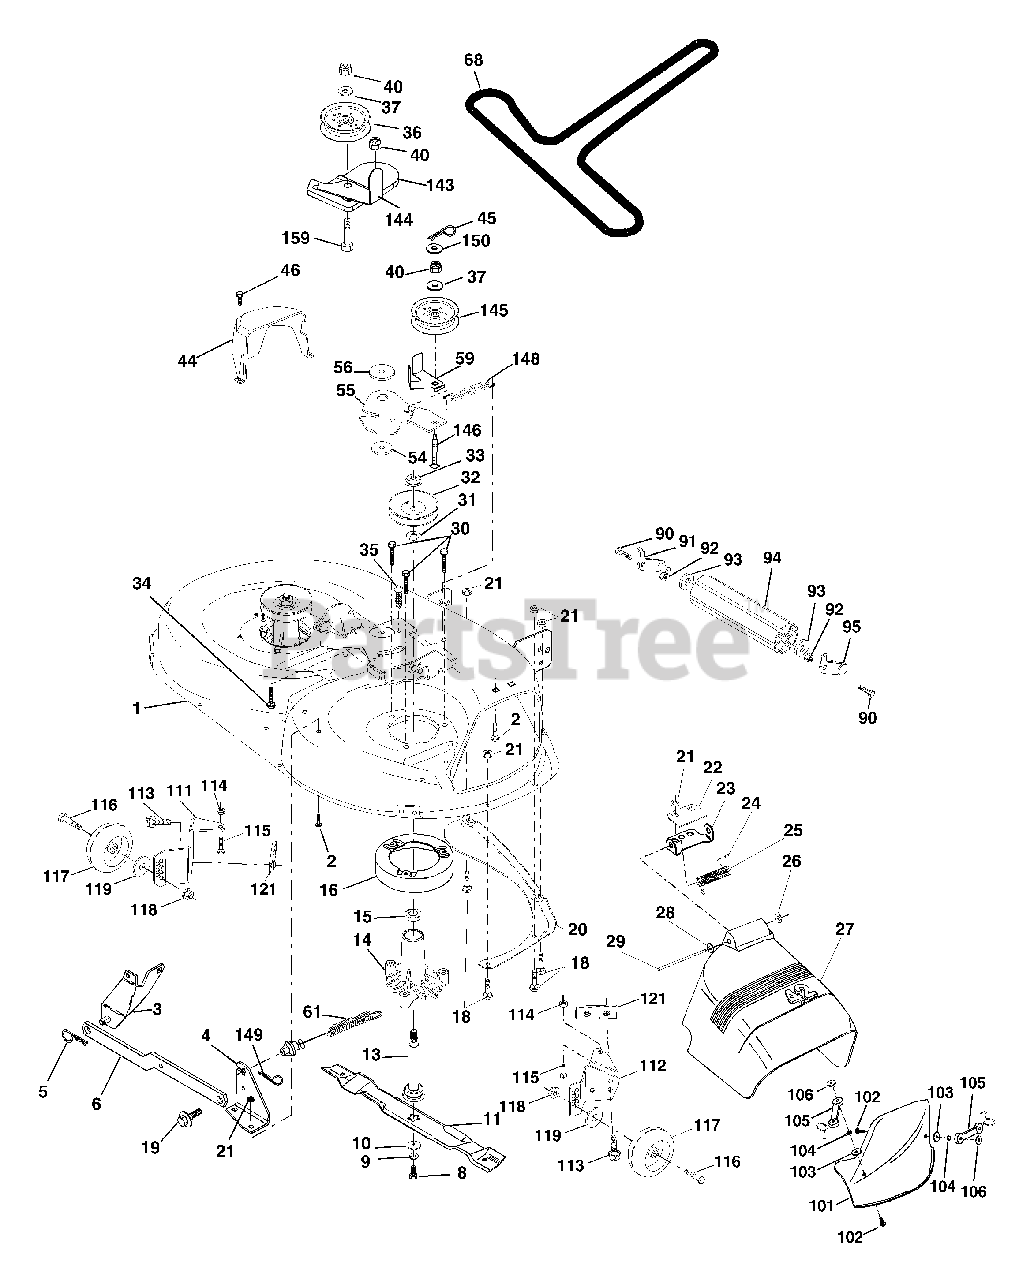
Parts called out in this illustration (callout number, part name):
1	Mower Deck Assembly, 42"
2	Bolt
3	Bracket Assembly,Sway Bar, Front
4	Bracket Sway Bar 38/42" Deck
5	Retainer Spring
6	Arm, Suspension, Rear
8	Bolt, Hex 3/8-24 x 1.25 Gr. 8
9	Washer, Lock
10	Washer,Hardened
11	Blade Mower 42" High Perf.
11	Blade, Mulching
13	Shaft Assembly, Mandrel, Vented
14	Housing, Mandrel, Vented
15	Bearing, Ball, Mandrel
16	Stripper, Vented Mower Deck
18	Bolt, Carriage 5/16-18 x 5/8
19	Bolt, Shoulder
20	Baffle, Vortex
21	Nut Crownlock 5/16-18 UNC
22	Stiffener Bracket
23	Bracket, Deflector
24	Cap, Sleeve
25	Spring, Torsion, Deflector
27	Shield, Deflector
28	Washer 11/32 x 5/8 x 16 Ga.
29	Rod, Hinge
30	Screw Thdrol Washer Head
31	Washer, Spacer
32	Pulley, Mandrel
33	Nut, Toplock, Flanged
35	Fastner, Christmas Tree
36	Pulley, Idler, Flat
37	Washer 13/32 x 13/16 x 16 Gauge
40	Nut Crownlock 3/8-16 UNC
44	Guard, Mandrel, L.H.
45	Retainer
46	Screw, Thd. Roll 1/4-20 x 5/8
54	Washer,Hardened
55	Arm, Idler
56	Spacer, Retainer
59	Guard, TUV Idler
61	Spring Ext Elect Clutch 42" Dck
90	Bolt Fin Hex 3/8-16 Unc x 1
91	Bracket Asm Noseroller Lh
92	Nut Lock Hex w/Ins. 3/8-16 Unc
93	Washer 17/32 x 7/8 x 16 Ga.
94	Roller Nose 38"-50"
95	Bracket Asm Noseroller Rh
101	Mulcher Cover
102	Screw
103	Washer #10
104	Washer, Lock
105	Latch Assembly, Bagger
106	Nut, Weld
111	Bracket, Gauge, Wheel L.H.
112	Bracket, Gauge, Wheel R.H.
113	Screw Tapping 5/16-18 Unc
114	Nut, Hex, Keps 5/16-18 UNC
115	Bolt, Carriage 5/16 UNC x 1/2
116	Bolt, Shoulder
117	Wheel,Gauge
118	Nut, Centerlock 3/8-16
119	Washer 3/8 x 7/8 x 14 Gauge
121	Bracket
143	Bracket Arm Idler 42"
144	Keeper Belt 42" Clutch Cable
145	Pulley Idler Flat
146	Bolt Carriage Idler
148	Spring Return Idler
149	Retainer Spring Yellow Zinc
150	Washer 9/32 x 3/4 x 16 Ga.
159	Bolt Rdhd Sqn 3/8-16 UNC x 1- 3/4
